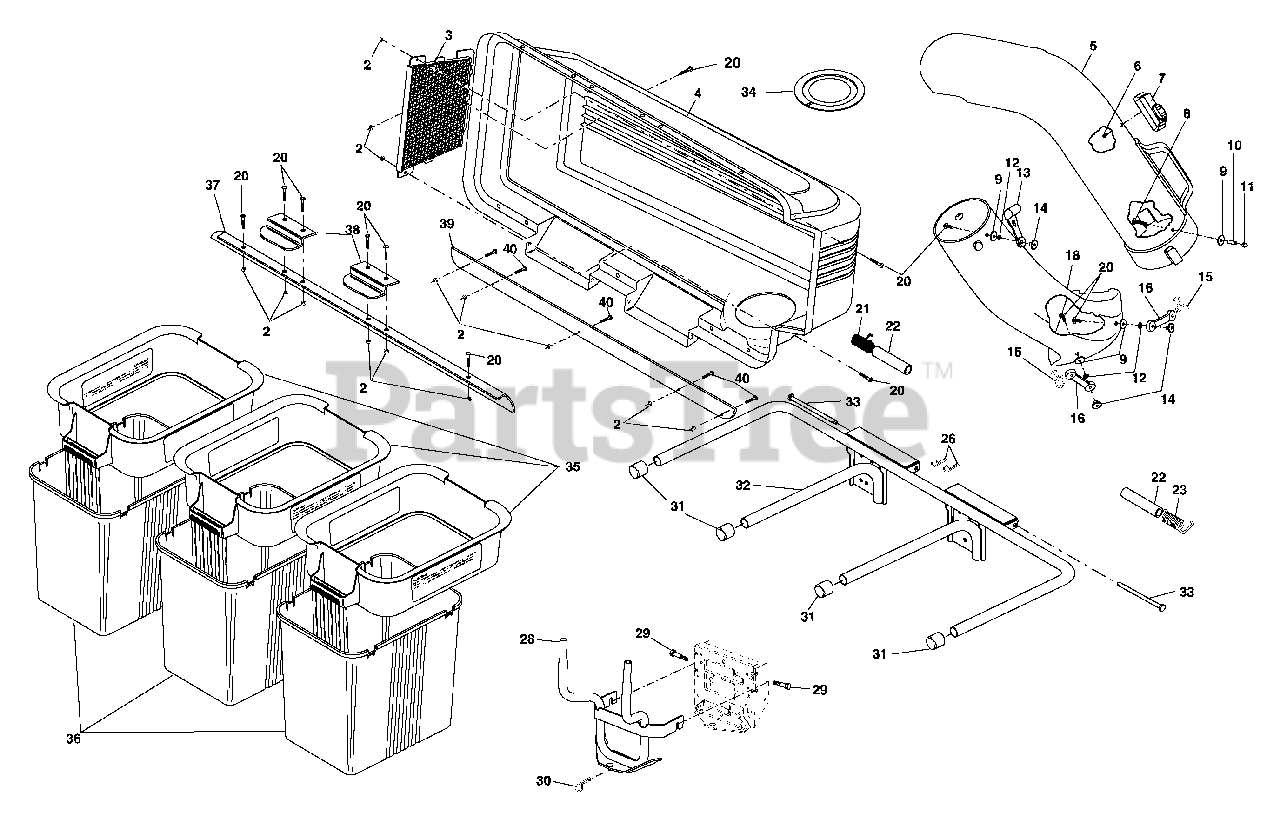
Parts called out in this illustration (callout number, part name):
2	Nut, Crownlock #10-24
3	Screen, Cover
4	Cover
5	Chute, Upper
6	Screw, Special #10-14x1/2
7	Dump Bag Indicator
8	Screw, #10-24 x 1-1/8
9	Washer 3/16x3/4x16 Ga.
10	Spacer, Split
11	Nut, Acorn #10-24
12	Washer, lock
13	Latch, Chute
14	Nut, Weld
15	Latch, Hook
16	Rubber, Latch
18	Chute, Lower
20	Screw #10-24 x 5/8
21	Spring, Cover L.H. (black)
22	Spacer, Cover
23	Spring, Cover R.H. (gray)
26	Spring, Retainer
28	Support Assembly
29	Shoulder Bolt, Self Tapping
30	Spring, Retainer
31	Plug, Tubing End
32	Bagger, Frame
33	Pin, Hinge
34	Gasket, Cover
35	Container, Top
36	Container, Bottom
37	Seal, Cover
38	Latch Handle, Cover
39	Strip, Reinforcement
40	Screw #10-24 x 1/2
